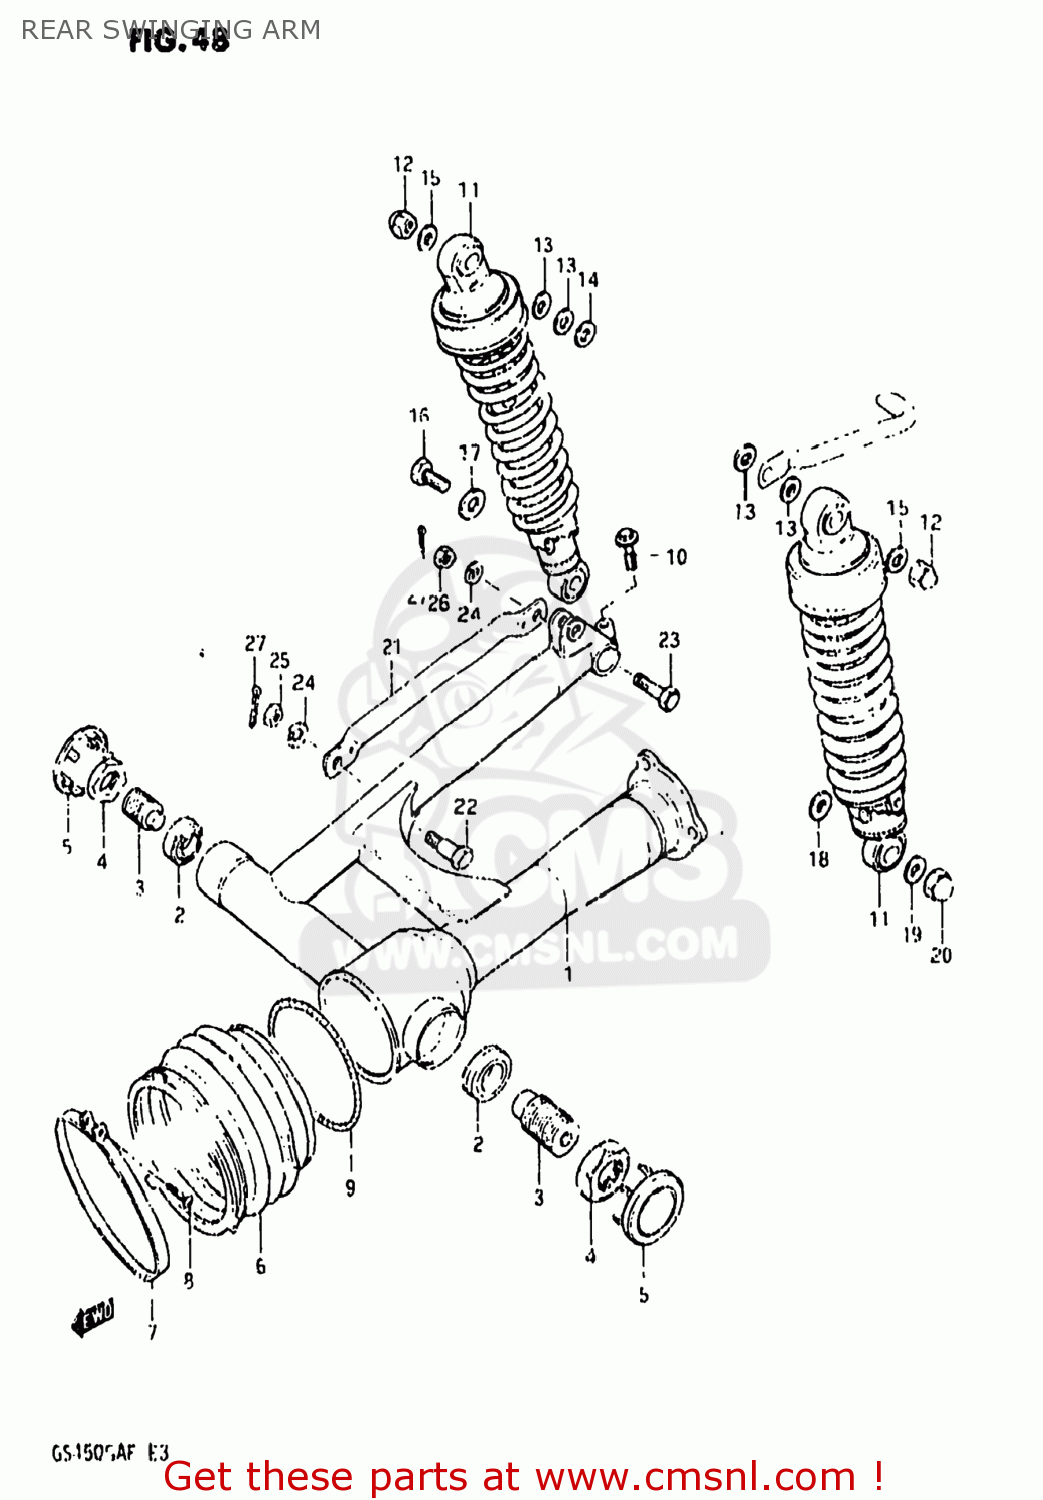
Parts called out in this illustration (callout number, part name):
1	SWING ARM ASSEMBLY,REAR
2	BEARING(15X35X11.75)
3	BOLT,REAR SWING ARM PIVOT
4	NUT (22MM)
5	CAP,PIVOT NUT
6	BOOT,PROPELLER SHAFT
7	CLAMP
8	SCREW 4X25
9	SPRING,PROPELLER SHAFT
10	BOLT
11	ABSORBER ASSEMBLY,REAR SHOCK
12	NUT
13	WASHER
14	WASHER (12.5X24X3.2)
15	WASHER
16	BOLT 12X33
17	WASHER (12.5X24X1.6)
18	WASHER
19	WASHER
20	NUT, LOWER LH
21	TORQUE LINK,REAR
22	BOLT(10X24.5)
23	BOLT(10X31)
24	LOCK WASHER
25	NUT
26	NUT
27	PIN 20X20
